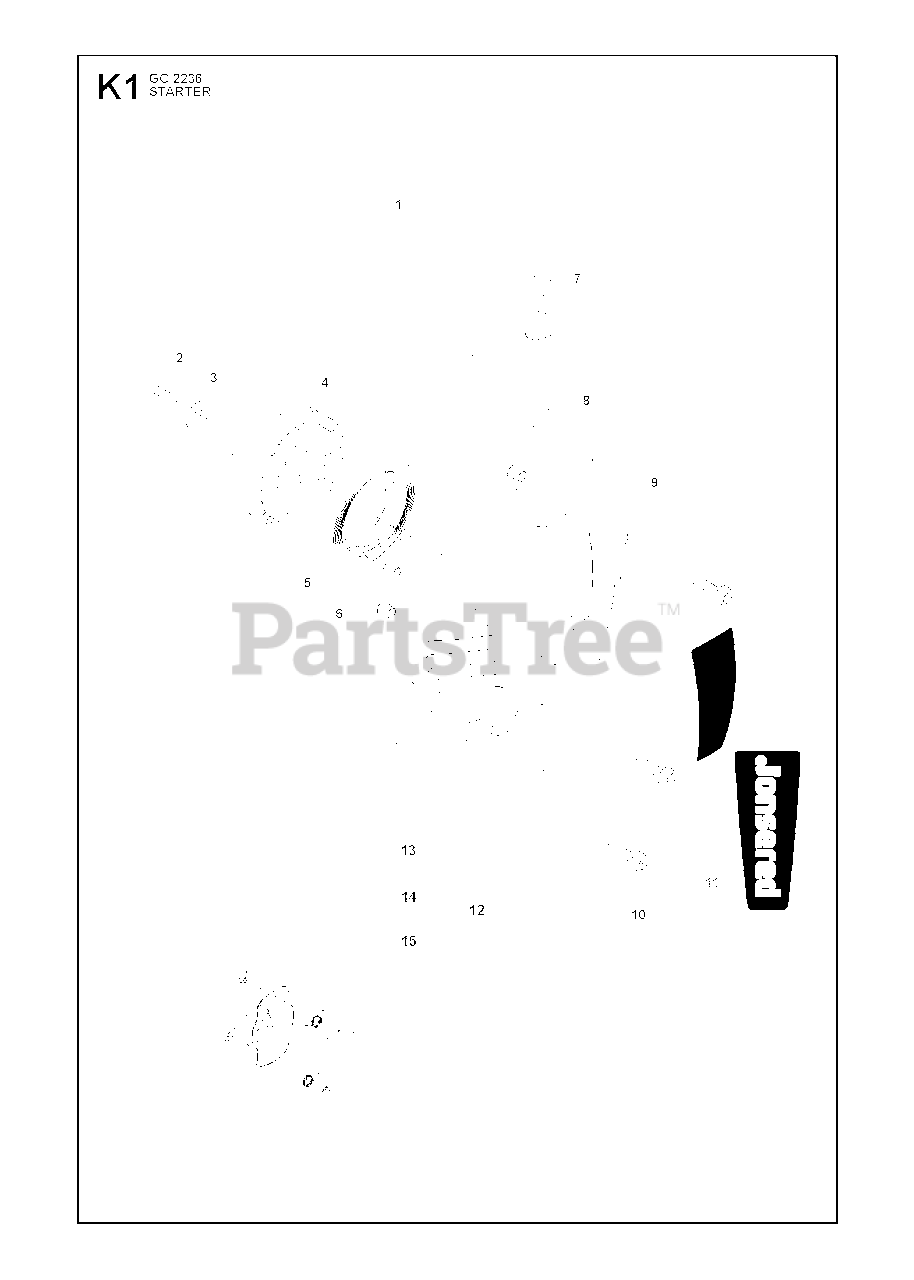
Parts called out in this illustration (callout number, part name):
1	STARTER HOUSING
2	SCREW
3	WASHER
4	%STARTER PULLEY
5	STARTER SPRING
6	SLEEVE
7	STARTER ROPE
8	HANDLE
12	STARTER PAWL BRIDGE
13	E-RING 4
14	SPRING
15	STARTER PAWL
